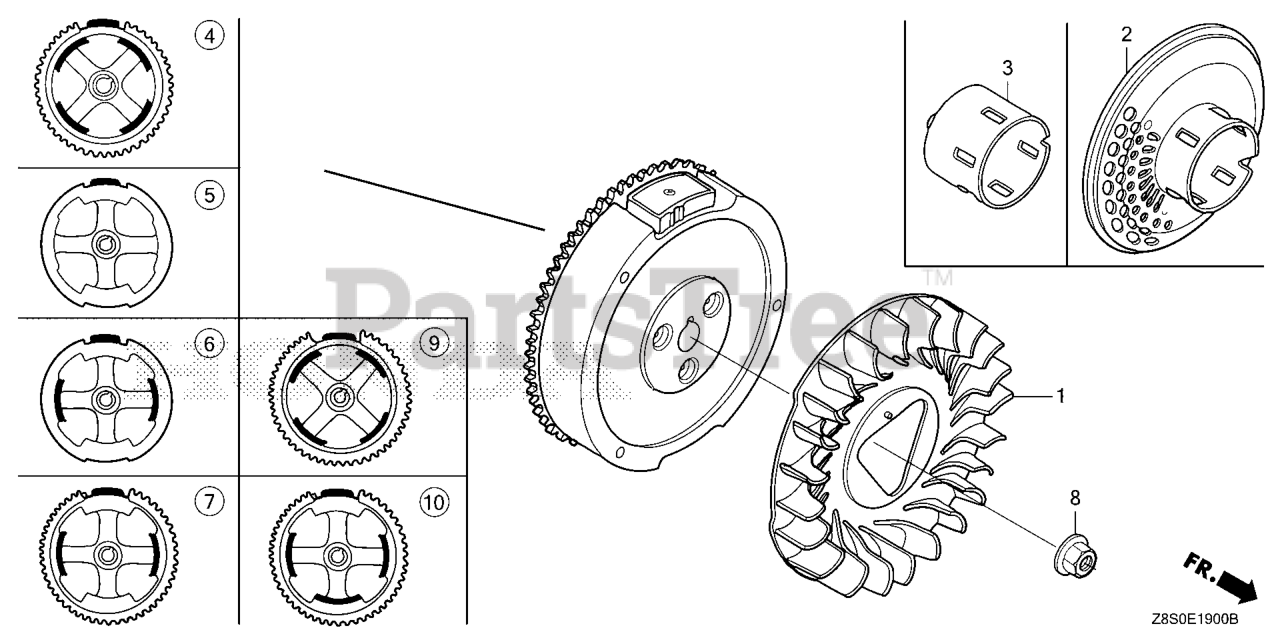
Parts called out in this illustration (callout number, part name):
1	FAN, COOLING
2	PULLEY, STARTER (SCREEN GRID)
6	FLYWHEEL (LAMP)
8	NUT, SPECIAL (16MM) (1)
